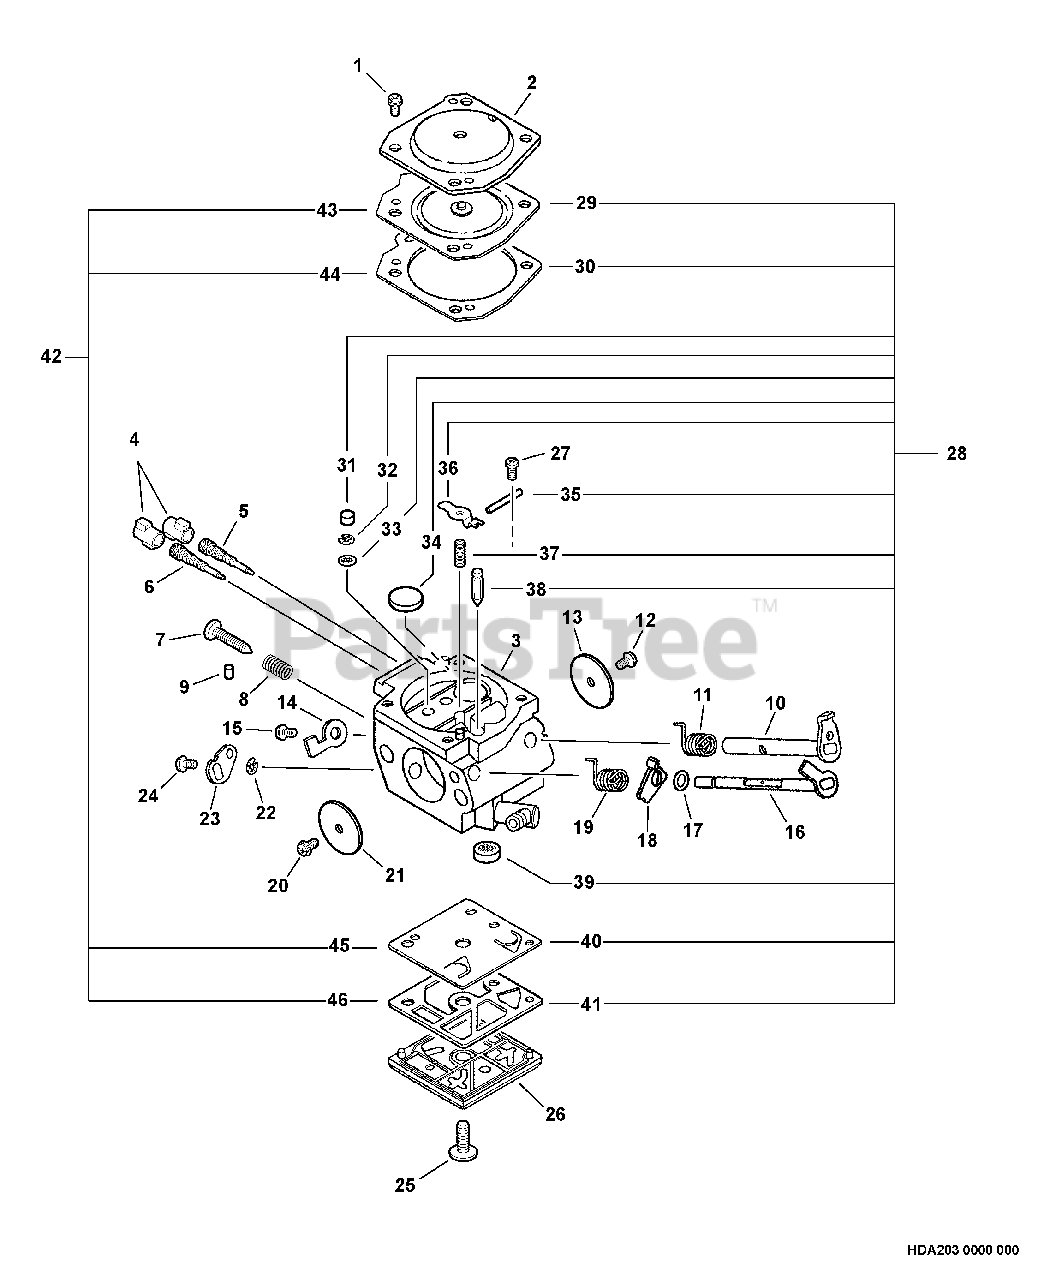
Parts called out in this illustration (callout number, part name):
2	COVER, METERING
3	BODY, CARBURETOR
4	CAP, LIMITER
5	NEEDLE - MIXTURE
6	NEEDLE - HIGH SPEED
7	SCREW, IDLE ADJUST
8	SPRING, IDLE ADJUST
10	SHAFT, THROTTLE
11	SPRING, THROTTLE RETURN
13	VALVE, THROTTLE
14	STOP, THROTTLE
16	SHAFT, CHOKE
18	LEVER, FAST IDLE
19	SPRING, CHOKE RETURN
21	VALVE, CHOKE
22	RING, RETAINING
23	LEVER, CHOKE
25	SCREW, PUMP COVER
26	COVER, PUMP
27	SCREW, METERING LEVER PIN
28	REPAIR KIT
29	DIAPHRAGM, METERING
30	GASKET, DIAPHRAGM
31	PLUG, CUP
32	RING, RETAINING
33	STRAINER
34	PLUG, WELCH
35	PIN, METERING LEVER
36	LEVER, METERING
37	SPRING, METERING LEVER
38	VALVE, INLET NEEDLE
39	STRAINER
40	DIAPHRAGM, PUMP
41	GASKET, PUMP
42	DIAPHRAGM/GASKET KIT
43	DIAPHRAGM, METERING
44	GASKET, DIAPHRAGM
45	DIAPHRAGM, PUMP
46	GASKET, PUMP
